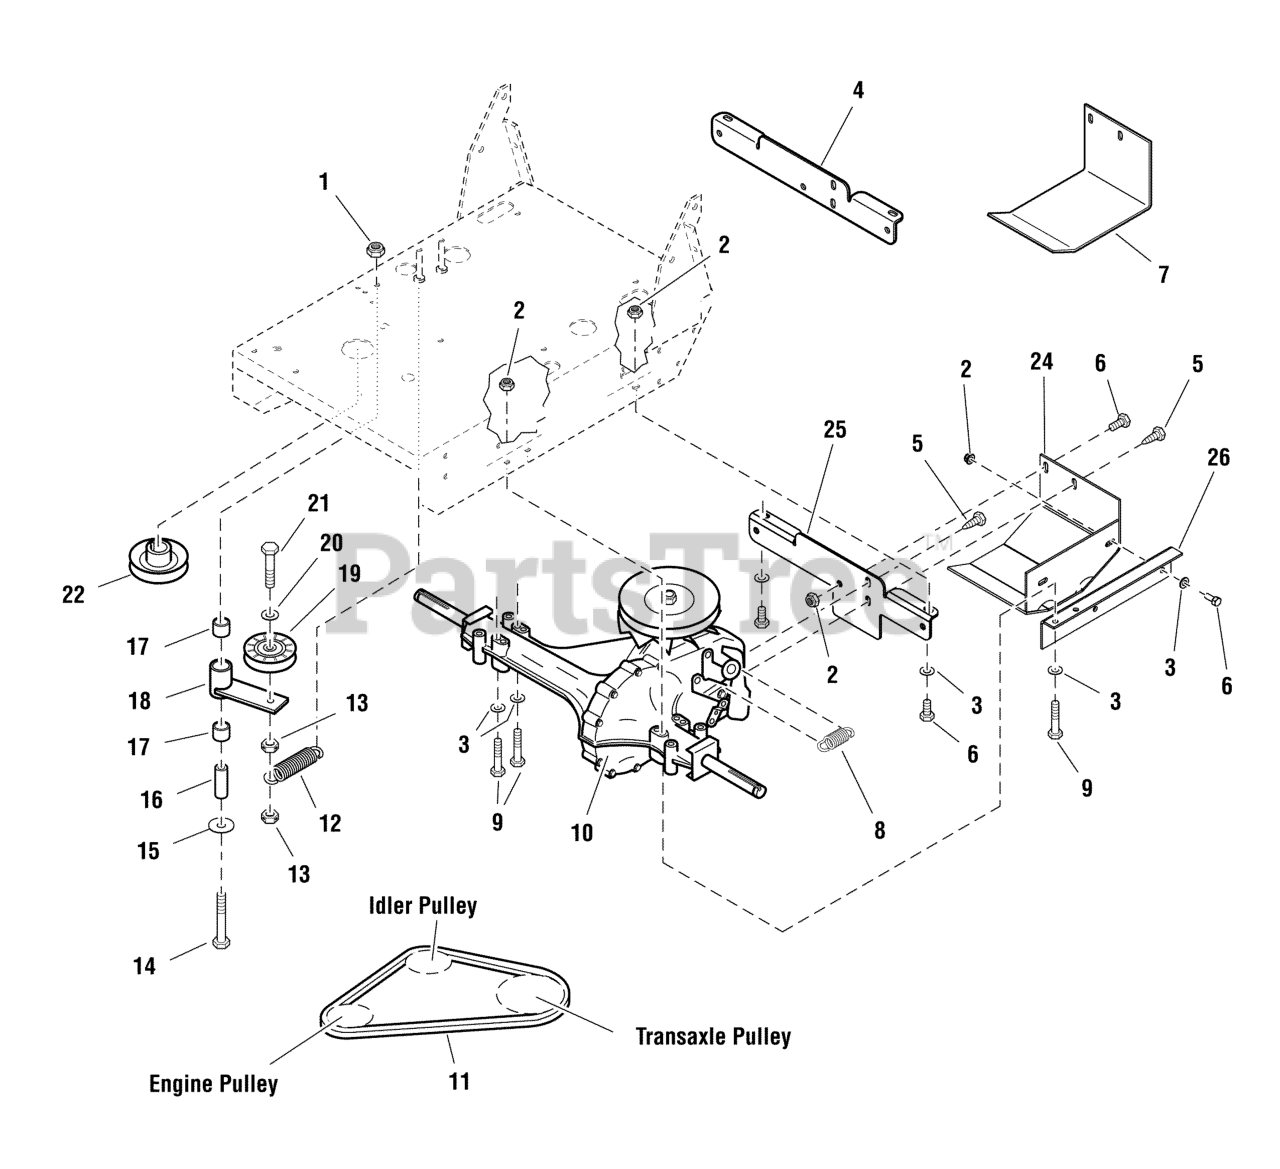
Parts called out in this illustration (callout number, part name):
1	NUT, 3/8-16 HEX NYLOCK FLANGE
2	NUT, 5/16-18 HEX NYLOCK FLANGE
3	WASHER, 5/16" SAE
4	BRACE, TRANSAXLE
5	BOLT, 5/16-18 X 3/4", SELF-TAPPING
6	BOLT, 5/16-18 X 1" GD5 YZ
7	SKID, PLATE, HC - RED
8	HYDRO RETURN SPRING (SV)
9	BOLT, 5/16-18 X 3" GD5 YZ
10	TRANSAXLE, HYDROSTATIC
11	BELT,# 46-4631
12	SPRING, EXTENSION
13	NUT, 3/8-16 HEX SIDE LOCK
14	BOLT, 3/8-16 X 3" GD5 CZ
15	WASHER, 3/8" FENDER
16	SPACER, .41 X .75 X 2.06
17	BUSHING, BRASS, 3/4 X 1 X 1
18	PIVOT ARM, WELDMENT
19	PULLEY, IDLER ASSEMBLY
20	WASHER, 3/8 SAE
21	BOLT, 3/8-16 X 2, GD5, CZ
22	PULLEY, DRIVE, 4.50 OD X 1.000 ID (SV)
24	WELD, CONTROL GUARD - RED
25	PLATE, TRANS BRACE, HC - RED
26	PLATE, CONTROL GUARD GUSSET - RED
